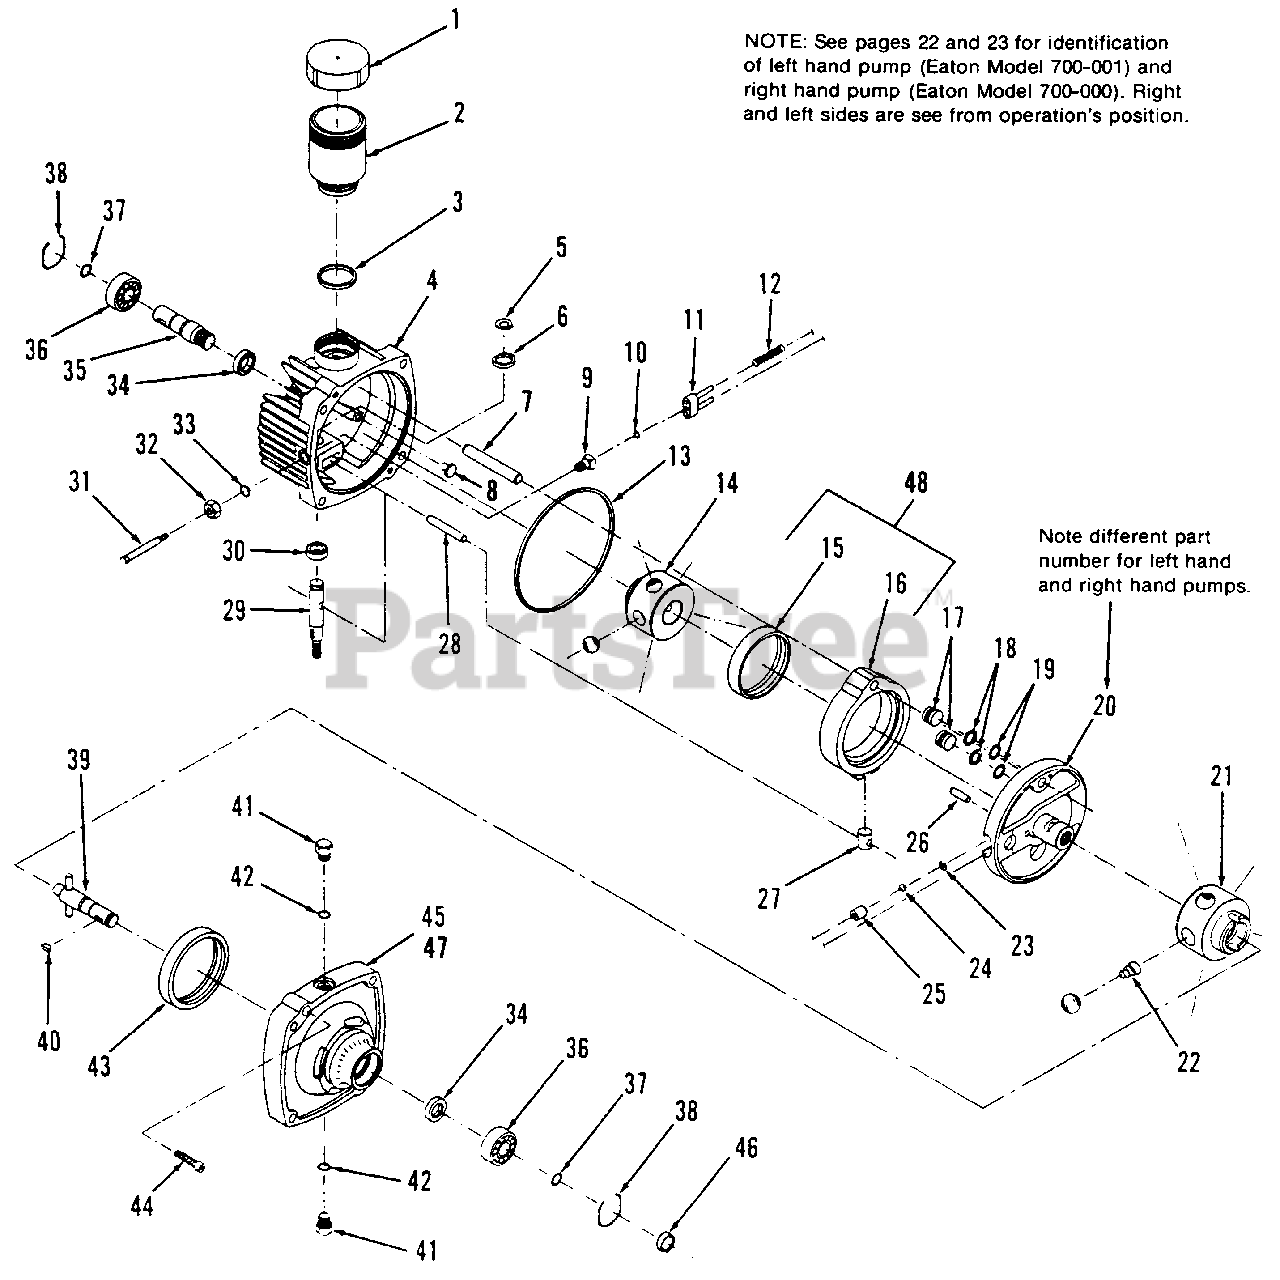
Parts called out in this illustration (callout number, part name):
1	RESERVOIR COVER, Sub-Assy.
2	RESERVOIR BODY
3	SEAL RING, Square Cut
4	COVER, Service Kit (Includes Ref. Nos. 5, 6, 7, 28, 29, 30 & 34)
5	RING, External Retaining
6	WASHER, Control Shaft
9	FITTING GUIDE, O-Ring, S.A.
10	O-RING
11	BRACKET, Pins, Sub-Assy.
12	SPRING, Valve
13	SEAL RING, Square Cut
14	PUMP ROTOR, Ball, Sub-Assy.
20	PINTLE, Sub-Assy. (Used on RH Eaton Pump Model 700-000) (Incl. Ref. Nos. 17, 18, 19, 23, 24, 25, 26)
20	PINTLE, Sub-Assy. (Used on LH Eaton Pump Model 700-001) (Incl. Ref. Nos. 17, 18, 19, 23, 24, 25, 26)
21	MOTOR ROTOR, Ball, Sub-Assy. (Includes Qty. 5 of Ref. No. 22)
22	SPRING, Piston
27	CAM RING, Insert
31	SHAFT, Dump Valve
32	NUT, Gasket, Sub-Assy.
33	O-RING
34	SEAL, Oil
35	SHAFT, Input
36	BEARING, Ball (Input)
38	RING, Retaining
39	OUTPUT SHAFT, Sub-Assy.
40	* KEY, Woodruff
41	O-RING, Sub Assy.
42	TUBE FITTING, O-Ring
44	CAPSCREW, Socket Hd.
47	BODY, Sub-Assy. (Includes Ref. Nos. 34, 36, 37, 38, 39, 43 & 45)
48	CAM RING, Sub-Assy. (Incl. Ref. Nos. 15 & 16)
